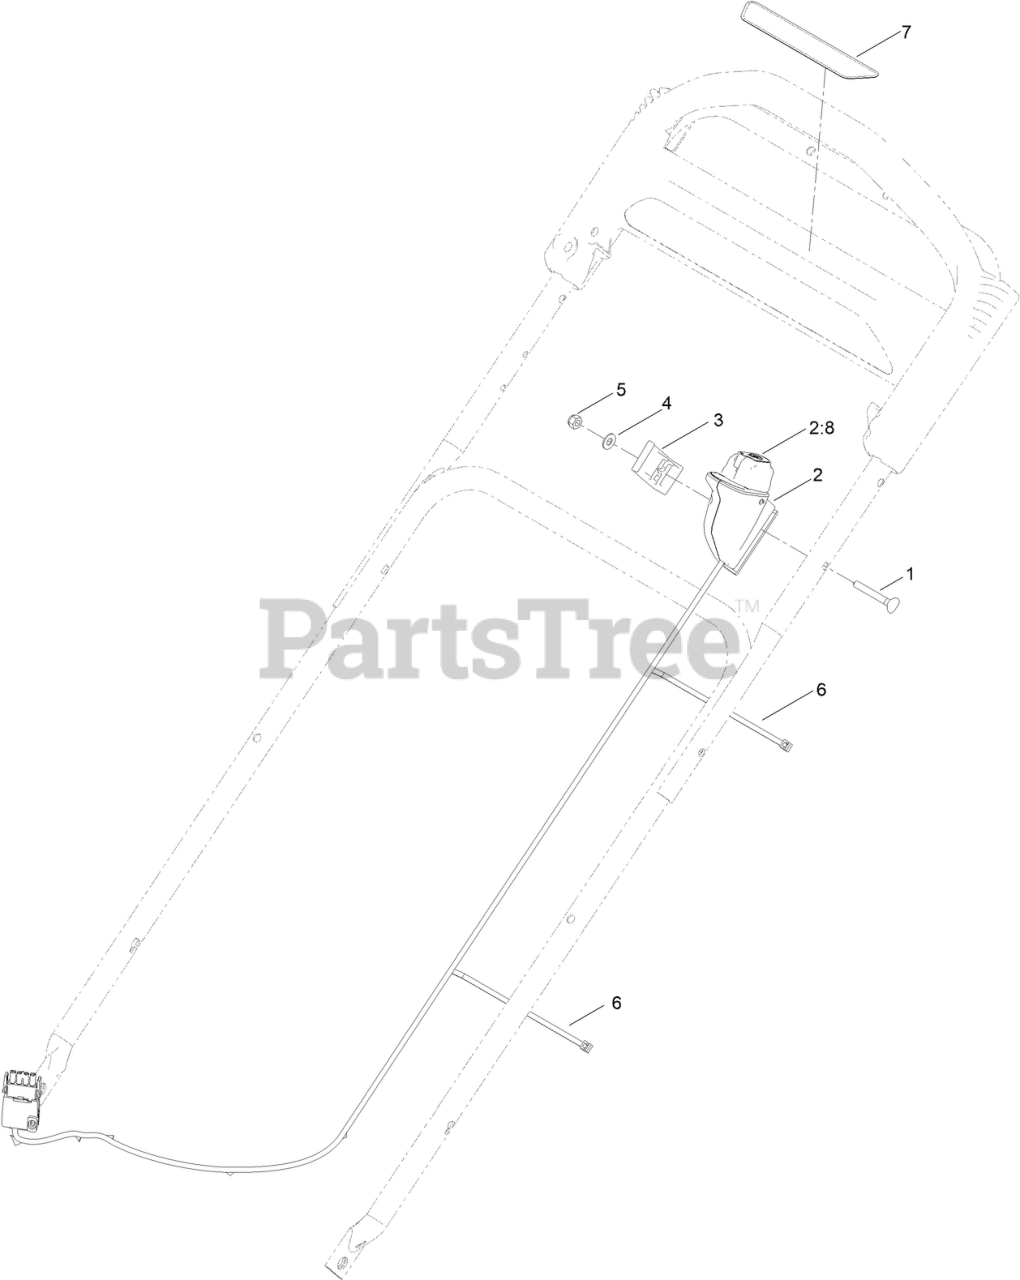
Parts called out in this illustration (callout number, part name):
1	BOLT-CARR
2	STARTER SWITCH ASM
2:8	DECAL CONTROL SPEED
3	CLAMP-CABLE
4	WASHER-FLAT
5	NUT-HEX
6	TIE-CABLE
7	DECAL-CONTROLS (60V, START)
